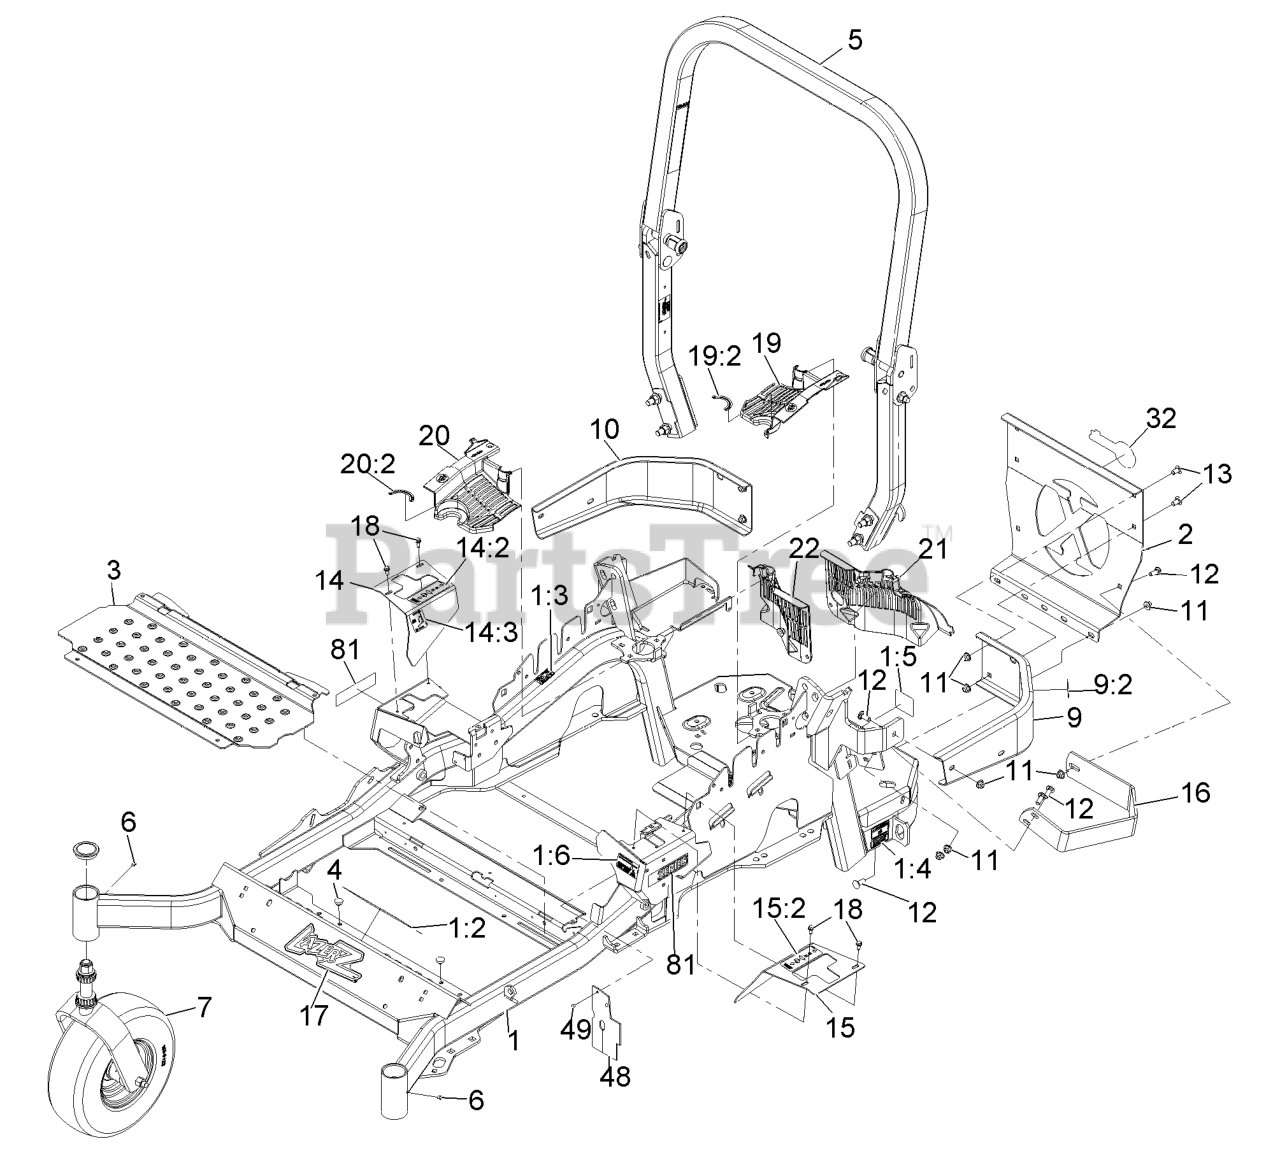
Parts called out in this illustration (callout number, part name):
1	MAIN FRAME ASM
1:2	DECAL-SLOPE
1:3	DECAL-CAUTION
1:4	DECAL-BELT DRIVE
1:5	DECAL-SPARK ARRESTER
1:6	DECAL-FUEL FILL
2	PLATE,REAR GUARD
5	ASM,ROPS SERVICE EXMARK
7	Caster Wheel Asm
9	LH BUMPER ASM
9:2	DECAL-CAUTION
10	BUMPER-RH
11	NUT-HF, NI
12	SCREW-CARR
13	SCREW-CARR
14:2	DECAL-MOTION CONTROL
15	LH MOTION CONTROL COVER ASM
15:2	DECAL-MOTION CONTROL
17	DECAL,LAZER MODEL
18	SCREW-HWH
19	LH HYDRO GUARD ASM
19:2	DECAL-HYDRO OIL
20	RH HYDRO GUARD ASM
20:2	DECAL-HYDRO OIL
21	GUARD-HYDRO, REAR (LH)
22	GUARD-HYDRO, REAR (RH)
48	DEFLECTOR-AIR FLOW
49	RIVET-POP
81	DECAL-X-SERIES
